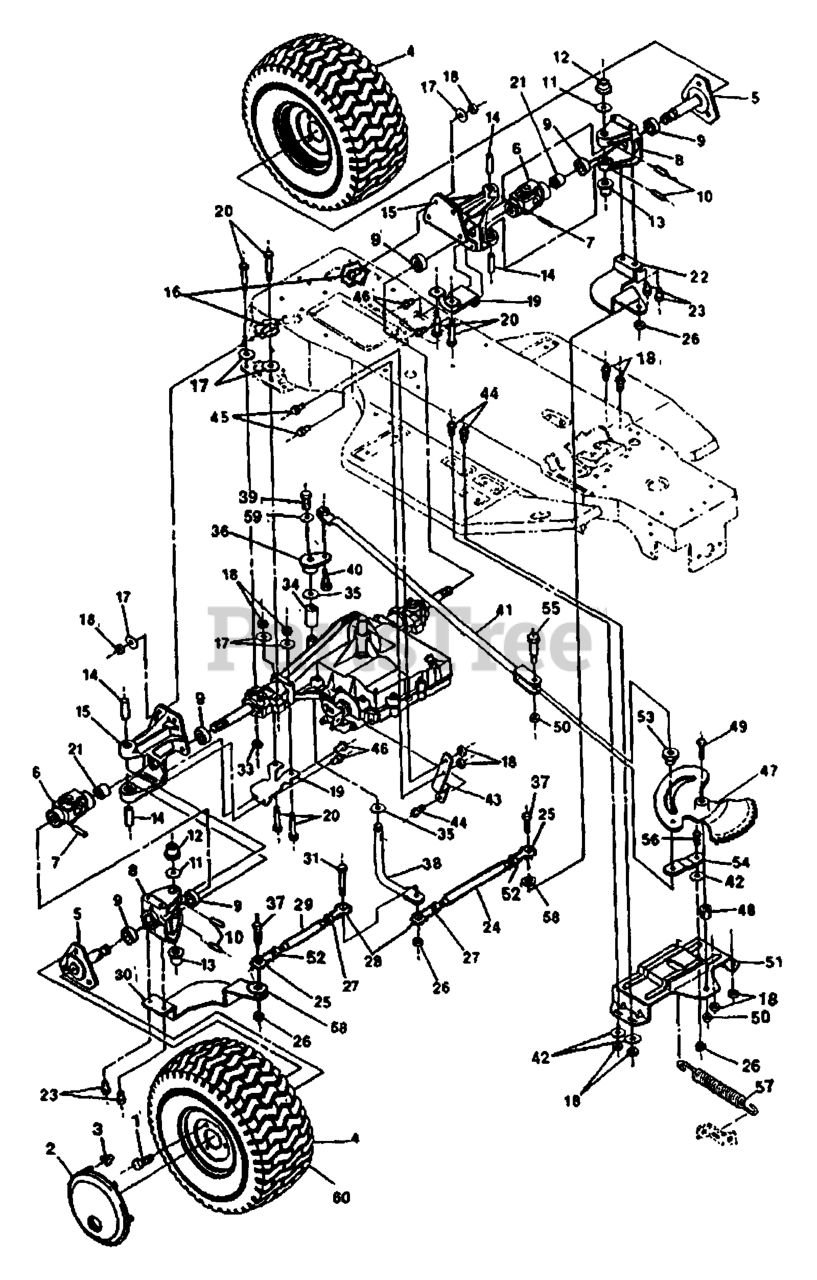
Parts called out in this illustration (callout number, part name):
4	WHEEL CPL.
5	REPL BY 533 31 54-80
6	JOINT ASSEMBLY
17	WASHER
18	NUT
20	SCREW
25	LINK, L.H.
26	NUT
27	NUT
31	SCREW
33	NUT
35	WASHER
36	PIN
38	LINK
40	SCREW
42	WASHER
43	BRACKET
44	SCREW
45	SCREW
46	SCREW
47	GEAR, STEERING
49	SCREW
50	NUT
51	PLATE
53	PIN
54	LINK
57	SPRING
58	WASHER 3/8ä
59	WASHER
